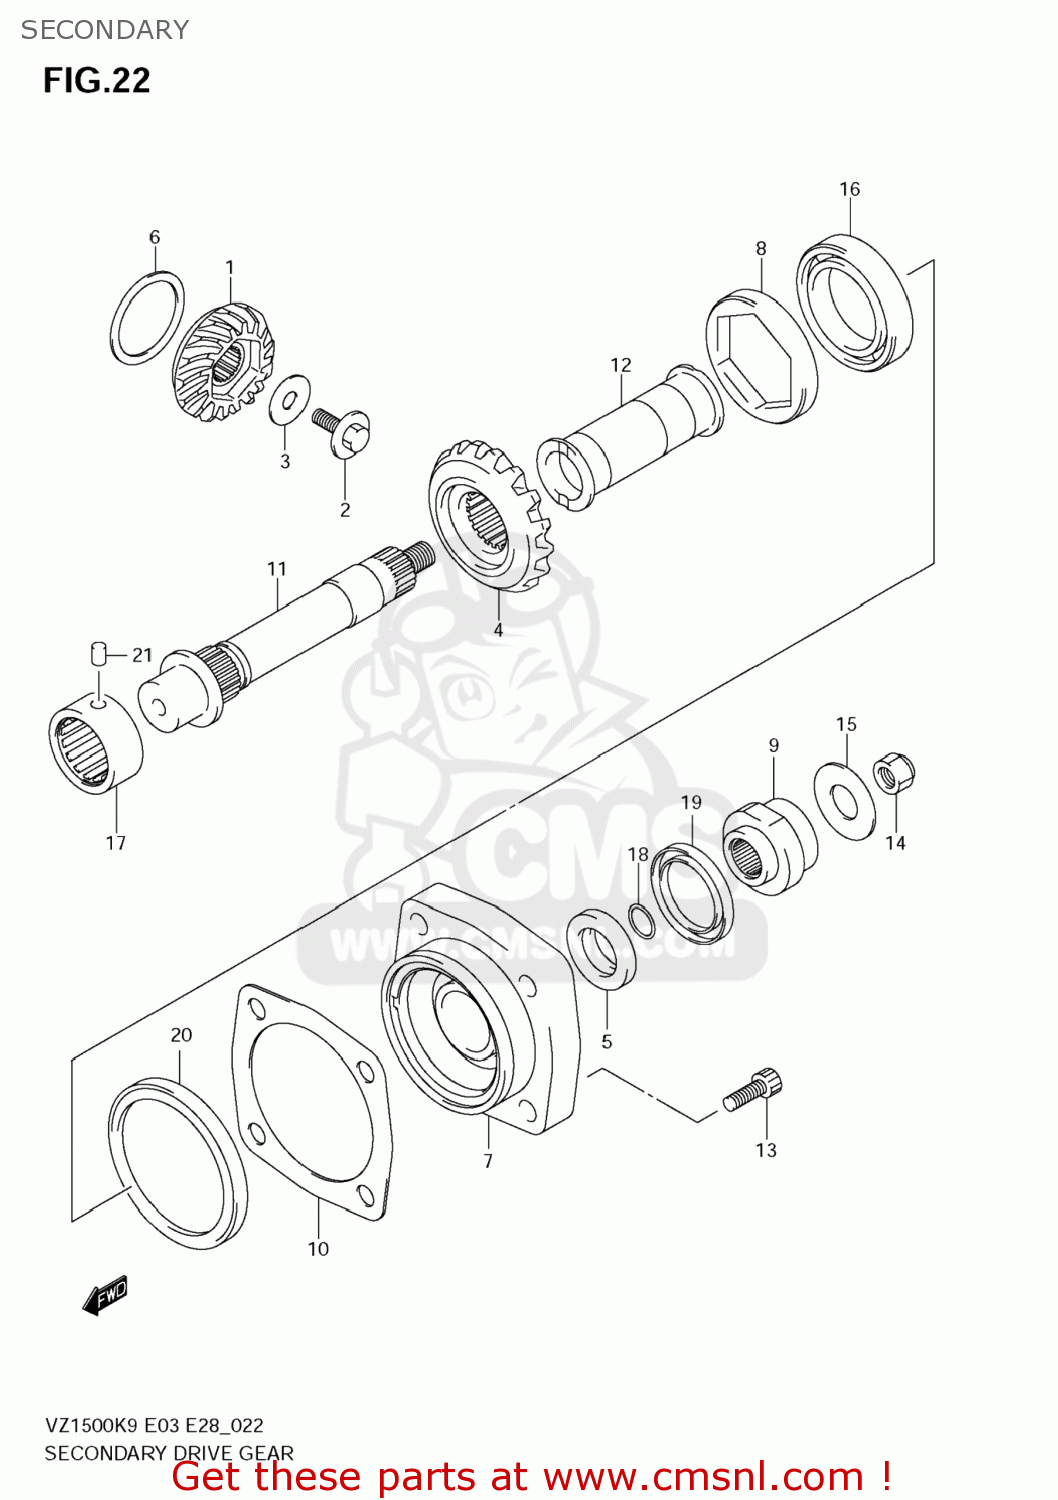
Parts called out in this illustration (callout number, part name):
1	GEAR,SECONDARY DRIVE
2	BOLT(12X24)
3	WASHER
4	GEAR,SECONDARY DRIVEN
5	SPACER,PRIMARY SHAFT
6	SHIM SET,SEC DRIVE
7	HOUSING,SEC DRIVEN BEARING
8	STOPPER,SEC DRIVEN BEARING
9	COUPLING,SEC DRIVEN BEVEL
10	SHIM SET,SEC DRIVEN
11	SHAFT,SECONDARY DRIVEN BEVEL
12	SPACER,SEC DRIVEN BEVEL
13	BOLT(10X30)
14	NUT
15	WASHER(16.5X36X4)
16	BEARING(28X68X18)
17	BEARING(32X50X22)
18	O RING(D:2.4,ID:24.7)
19	SEAL,OIL(38X54X6)
20	SEAL,OIL(76X84X7)
21	PIN
